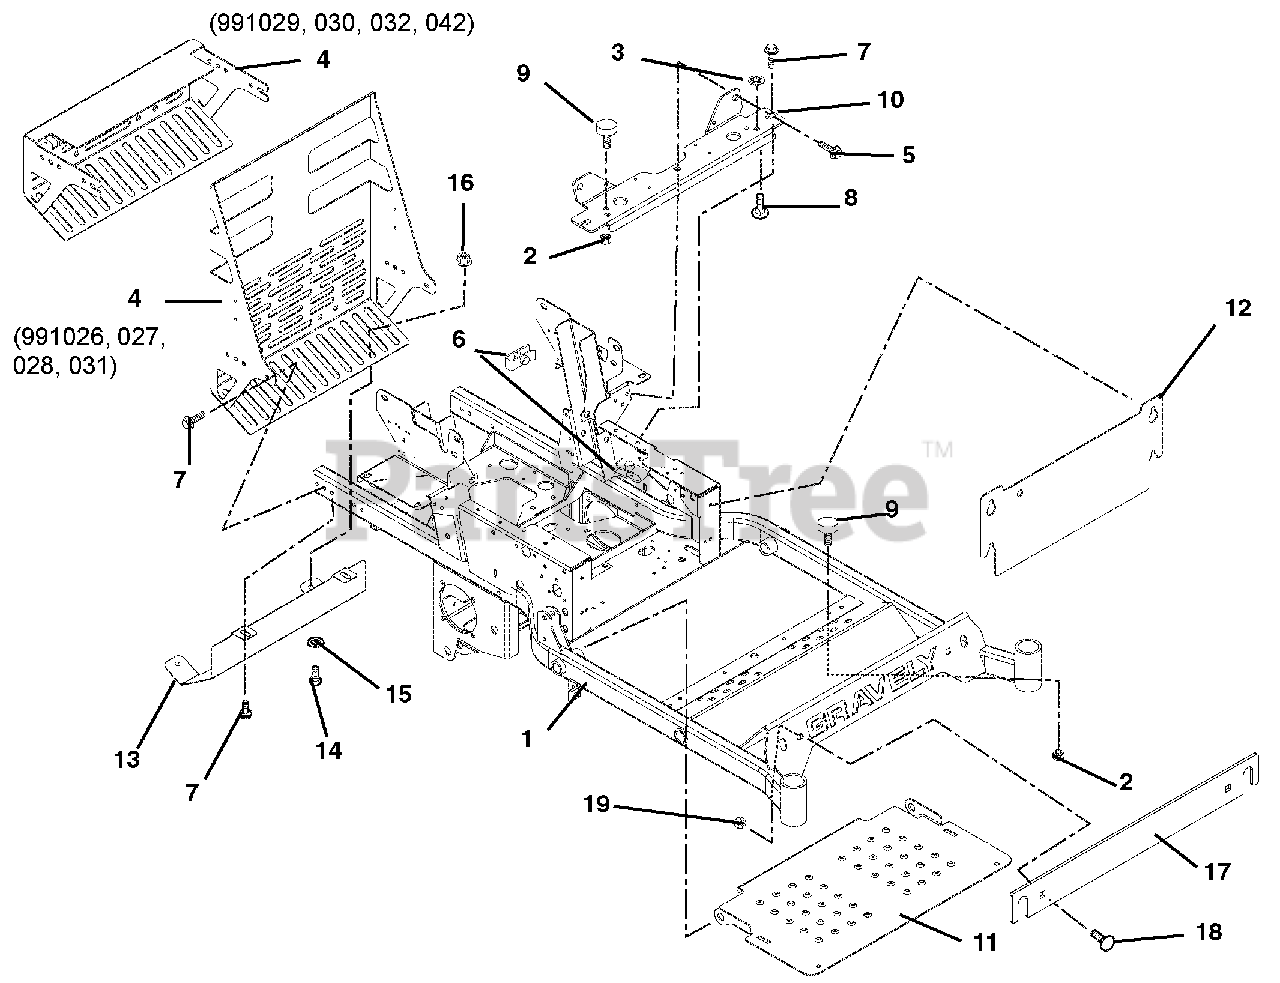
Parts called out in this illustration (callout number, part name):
1	Intermediate-Z Frame (991026, 027, 028, 029, 030, 031, 032)
2	Nut, Spin Lock Flange .312-18
3	Nut, Push .312
4	Bumper with Heat Shield (991026, 027, 028, 031)
5	Bolt, Serrated Flange Washer Head .38-16 x 1.00
6	Nut, Retainer .375-16 x .37
7	Screw, Tapping Hex Washer Head .38-16 x .50
8	Bolt, Round Head Square Neck .31-18 x 1.00 Grade 5
9	Bumper, Rubber
10	Seat Support
11	Footrest Panel
12	Access Panel
13	Heat Shield
14	Bolt-Hex .38-16 x .75 Grade 5
15	Washer-Flat-Steel .438 x 1.00 x .083
16	Nut-Locking-Top-Flange .38-16
17	Plate, Counterweight (991026, 027, 028, 029, 030, 031, 032)
18	Bolt, Round Head Square Neck .50-13 x 1.75 Grade 5 (991026, 027, 028, 029, 030, 031, 032)
19	Nut .50-13 Nyloc Flange
